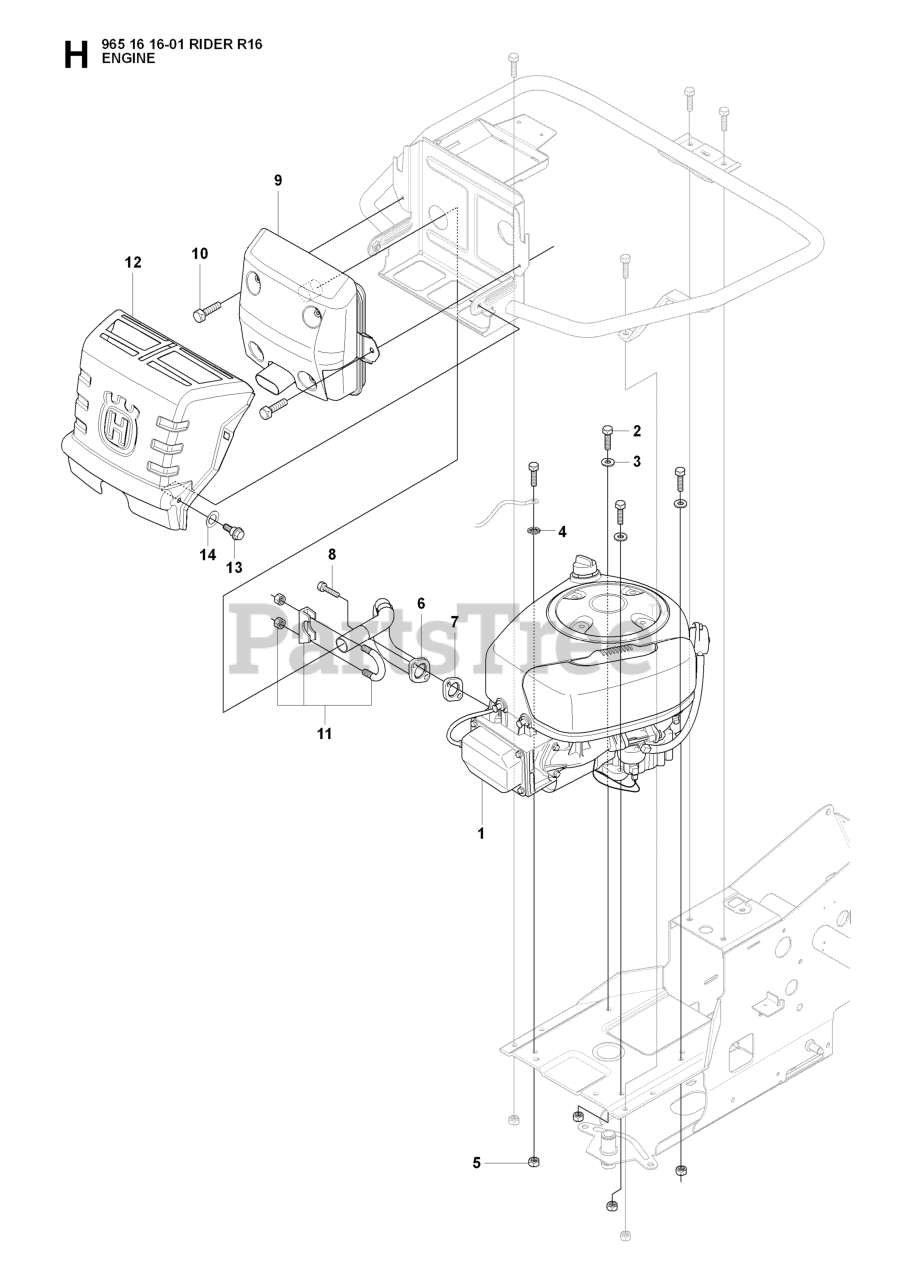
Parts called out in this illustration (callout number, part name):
3	WASHER BRB 8.4X17
5	LOCKNUT M8
9	MUFFLER ASSY
11	CLAMP
12	HEAT PROTECTOR
14	SPRINGWASHER
